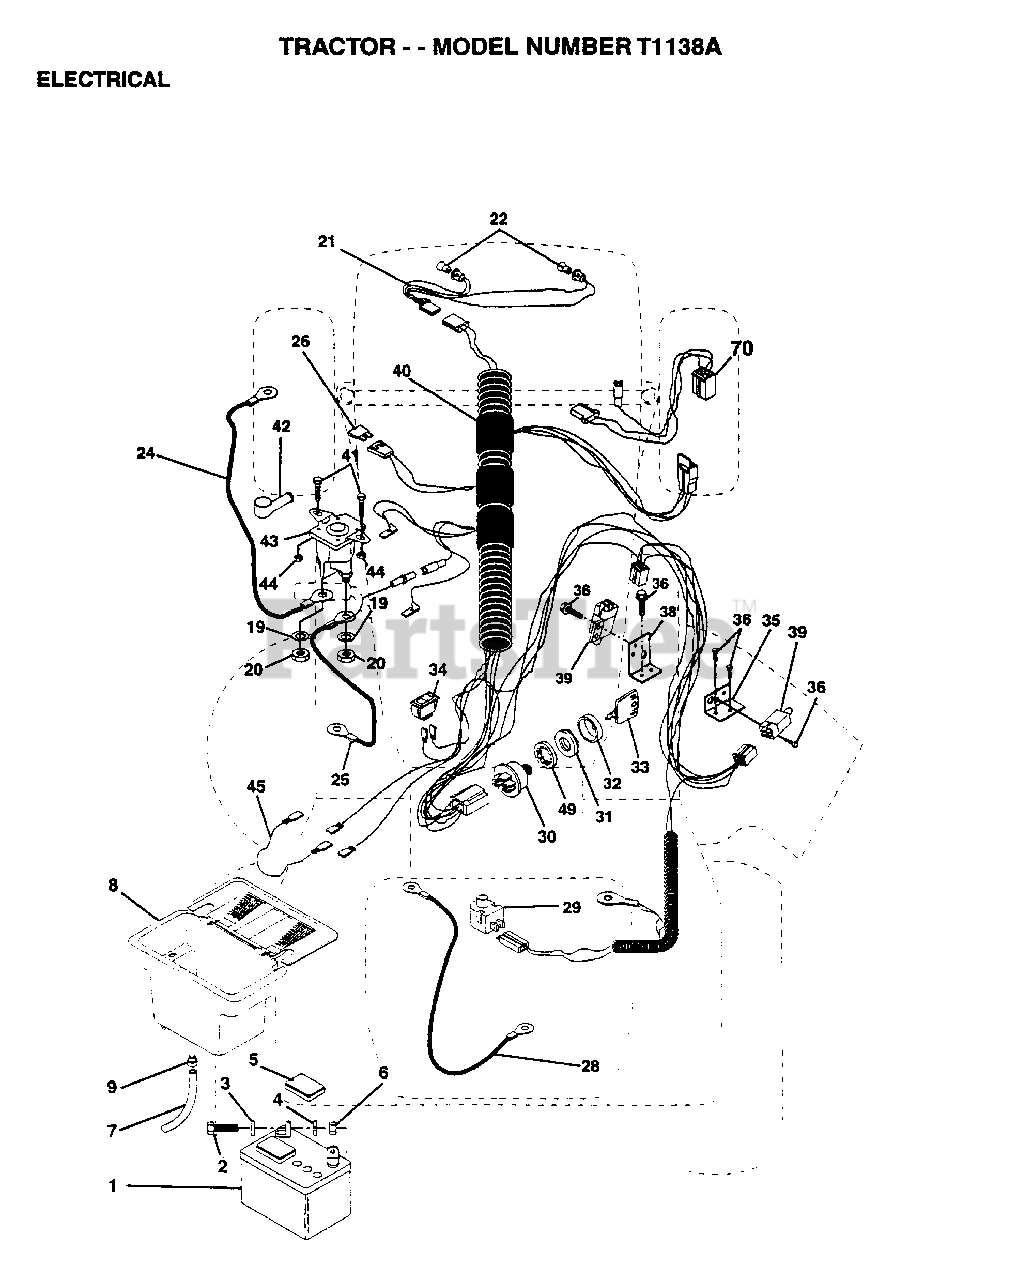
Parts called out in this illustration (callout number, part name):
2	BOLT LT
3	WASHER
4	LOCKWASHER
5	"CAP,BATTERY "
7	TUBE T
9	HOSE CLAMP T
20	NUT
21	"HARNESS,LIGHT SOC"
22	HEADLAMP BULB
24	"CABLE T, BATTERY"
25	CABLE.BTRY.6GA.RD
26	FUSE HYT
28	CABLE T
29	SWITCH SEAT
32	COVER KEY SWITCH
33	KEY STEEL DELTA
34	SWITCH LT
35	BRACKET LT
36	SCREW
38	BRACKET SWITCH IN
39	SWITCH INTERLOCKT
40	HARNESS.IGN.DASH.
41	BOLT.HX.1/4-20
44	NUT
45	ADAPTER AMMETER
49	LOCKWASHER
70	HARNESS ENG DUAL
